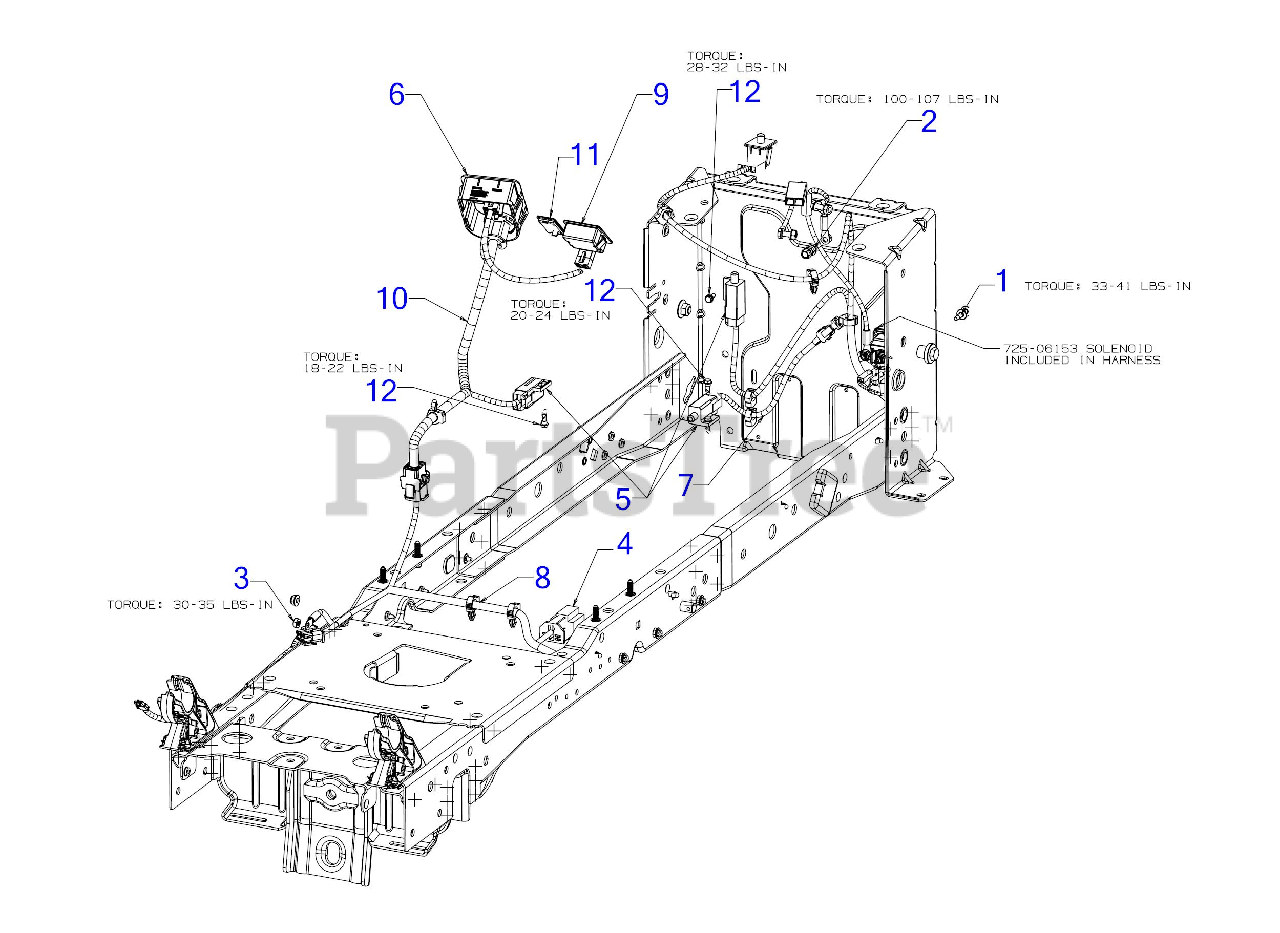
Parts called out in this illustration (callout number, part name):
1	SCREW M6-1 x .625
2	SCREW 1/4-20X.625
3	HEX NUT 1/4-20
4	3 POLE SWITCH ( NC-NO-NO)
5	INTERLOCK SWITCH (NO/NC)
6	IGNITION MODULE SWITCH RMC (MAN PTO BLK)
7	MAIN HARNESS M-PTO/RMC/HRMTR
8	REVERSE HARNESS
9	SERVICE MNDR/HOUR METER- BLUETOOTH
10	HARNESS
11	DASH PLUG
12	SHOULDER SCREW
